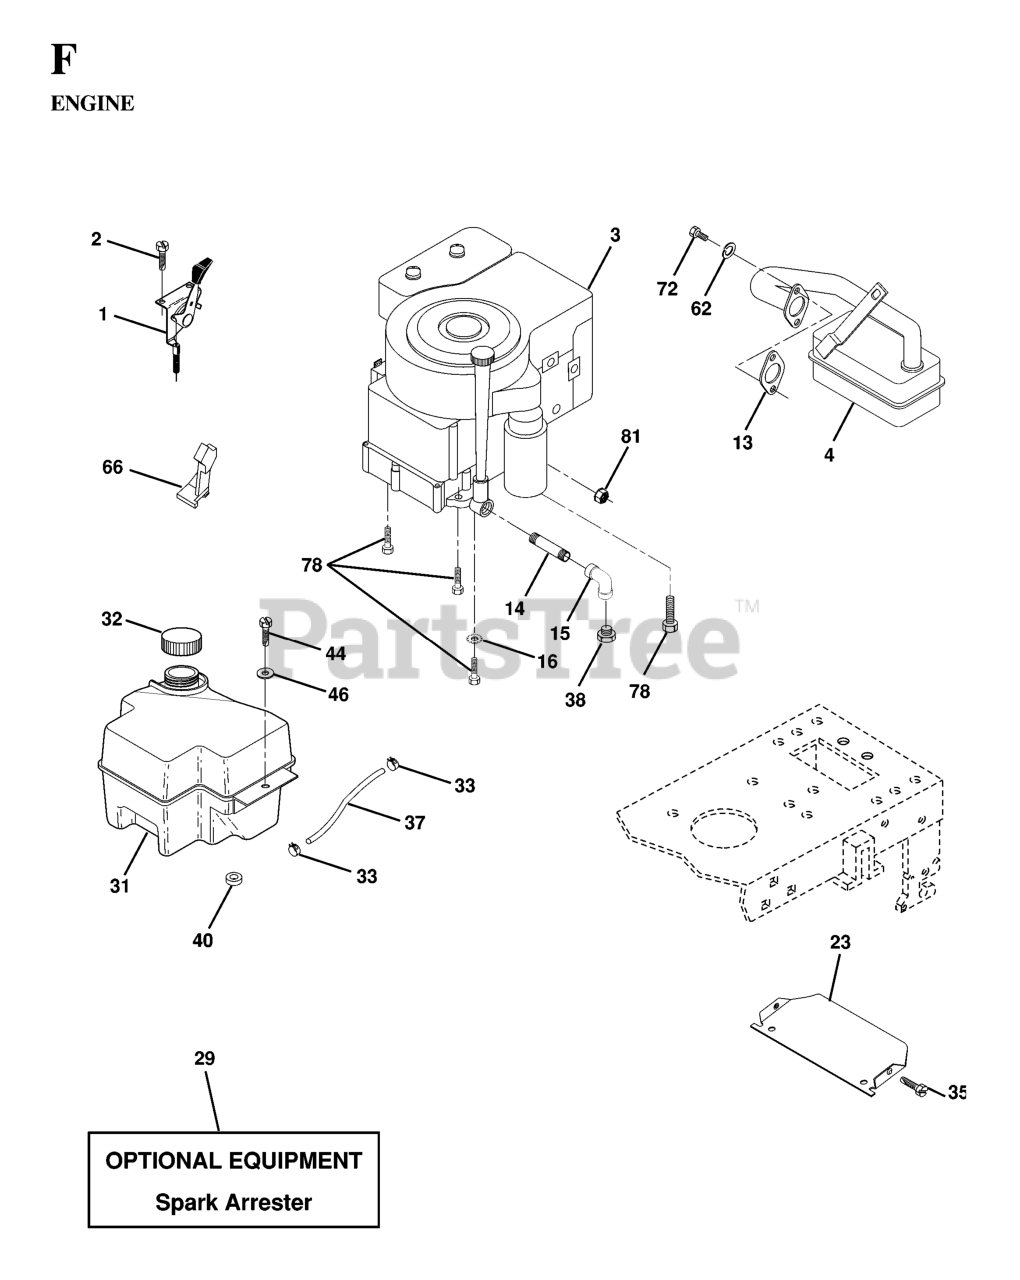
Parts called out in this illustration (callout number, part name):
1	CONTROL
2	SCREW LT
4	MUFFLER.SINGLE.B&S.10-12HP
13	GASKET.ENG.1.313 ID.TIN PLATED
14	Nipple Pipe 3/8 Npt X 3-1/2
15	ELBOW
16	LOCKWASHER
23	SHIELD HEAT
29	KIT.SPARK ARRESTOR 794945 B&S
31	FUEL TANK
32	FUEL CAP
33	HOSE CLAMP
35	SCREW.THDROL.5/16-18X3/4.TTY
37	LINE.FUEL.20
40	BUSHING.SNAP.NYL.BLK.
44	SCREW HEX CRT
62	WASHER.LOCK.HVY.HLCL.SPR.5/16
66	STOP THROTTLE
72	SCREW
78	SCREW
81	NUT FLANGE 1/4-20 STARTER NUT
